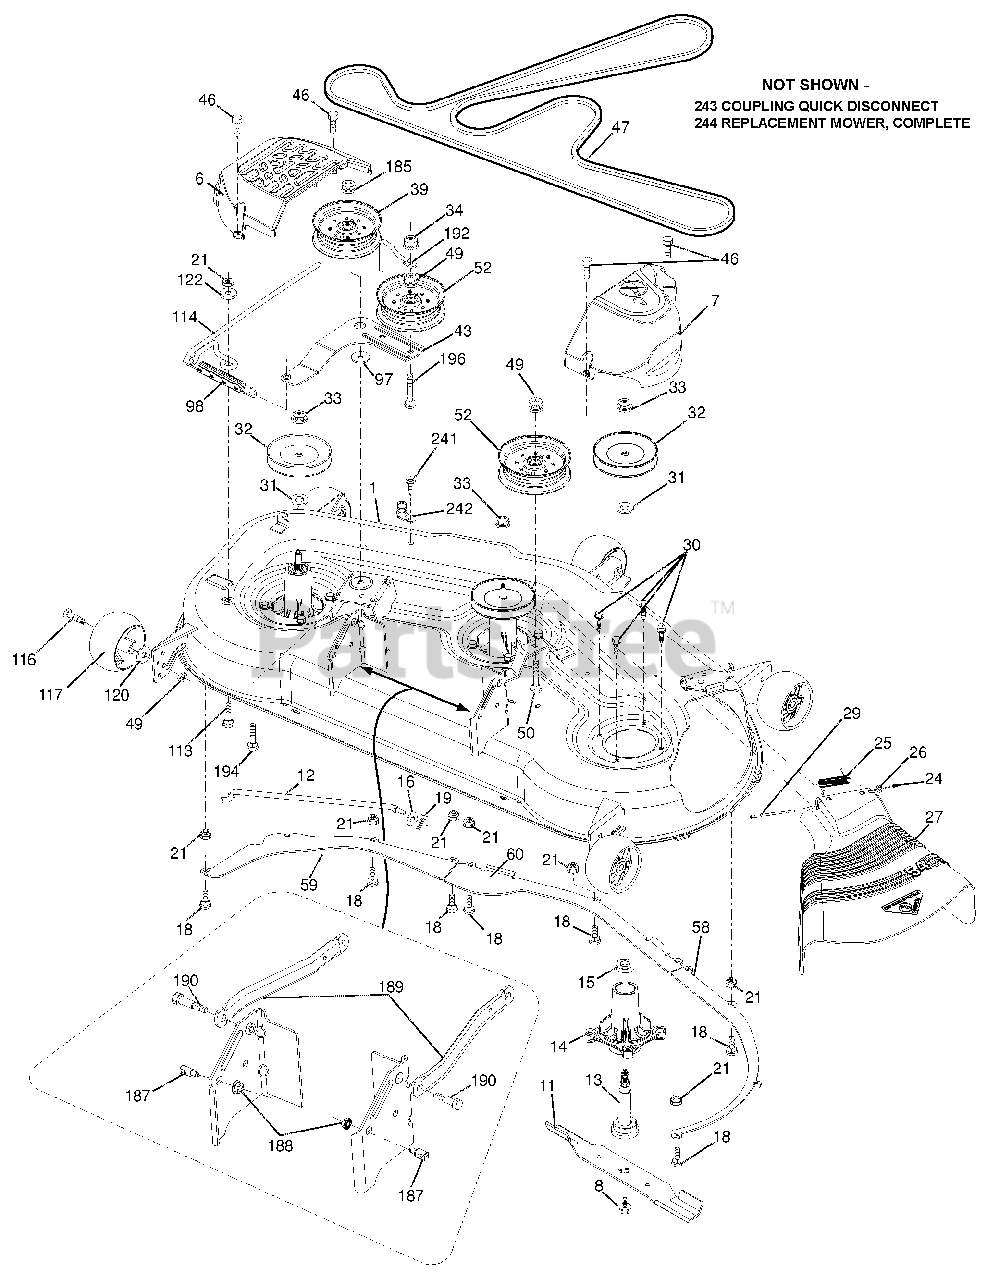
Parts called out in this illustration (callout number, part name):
1	DECK.WELDMENT.54"MS-422
6	COVER.MANDREL.LH.54"2006
7	COVER.MANDREL.RH.54"2006
8	BOLT/WASHER ASM.7/16-20.UNF
11	BLADE.BAGGING.54"
11	BLADE MULCHING
12	ROD ANTI-SWAY
13	SHAFT ASM.MANDREL.48/54"SVC
14	HOUSING.MANDREL.4PT.SERVICE
15	BEARING.BALL.MANDREL
16	Washer 13/32 x 13/16 x 12 Ga.
18	BOLT.RDHD.SQNK.5/16-18 X 5/8
19	PIN.COTTER.5/16.BOW TIE LOCK
21	Nut, Hex, Crownlock 5/16-18
24	CAP.SLEEVE..80X.112.BLK.MOWER
25	SPRING.TORSION.48"
26	NUT.PUSH.PHOS.& OIL
27	DEFLECTOR.BLACK.54"
29	ROD.HINGE.42/46"
30	SCREW.THD ROLL.DOD PT.HEX
31	WASHER.SPACER.MANDREL
32	MANDREL.PULLEYS.42,44,50
32	MANDREL ASM.48/54"
36	PULLEY.IDLER.4.50.RAW
39	PULLEY.IDLER.4.50.HUB.SPECIAL
43	ARM.ILDER
46	SCREW.THD.ROLL.1/4-20 X 5/8
47	BELT.DRIVE.54"2006
49	Nut, Hex, Flangelock 3/8-16
50	BOLT.RD.HD.SQ.NK.3/8-16UNC X 2
52	PULLEY.IDLER.4.50.RAW
58	BAFFLE.RIGHT.54"
59	BAFFLE.LEFT.54"
60	BAFFLE.CENTER.54"MOWER
97	WASHER.FLAT.HARDENED
98	SPRING.DRIVE.DECK.2006
113	BOLT.CARR.5/16-18UNC X 1
114	ROD.TENSION.RELIEF
116	BOLT.SHOULDER.3/8-16X3-5/8.GR5
117	WHEEL.GAUGE.RALLY.
120	WASHER.13/32 X 1-1/4 X 12 GA.
122	BUSHING.RELIEF.TENSION
185	NUT.LOCK.FLANGE.7/16-14.GR5
187	STUD.FASTNER.W/'D'ANTI-ROTATIO
188	Nut, Lock Hex Flange 5/16-18 u
189	ARM.SUSPENSION.MOWER.REAR
190	BOLT.SHOULDER
192	KEEPER.BELT.IDLER.54"TL
194	BOLT.CARR.SQNK.7/16-24 X 2
196	BOLT.RDHD.SQNK.3/8-16X2-1/2.G5
242	PORT WASHOUT
243	COUPLING QUICK CONNECT
244	54" REPLACEMENT MOWER COMPLETE
